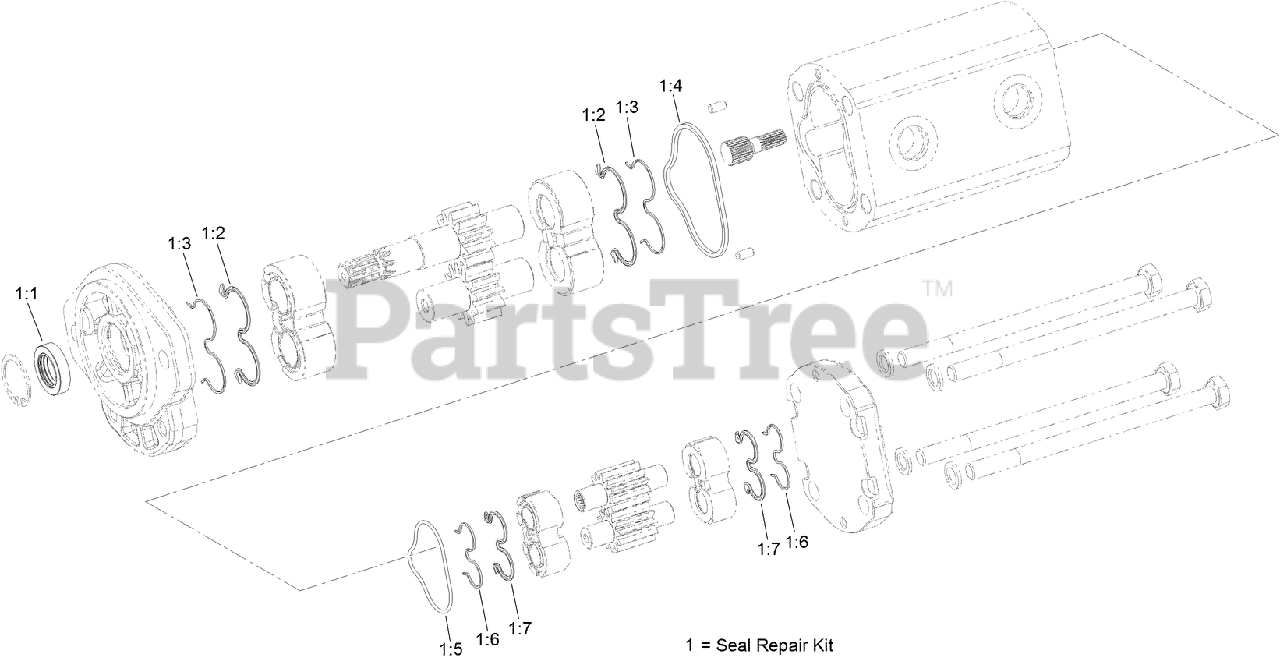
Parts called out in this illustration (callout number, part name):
1	SEAL KIT
1:1	SEAL-Shaft
1:2	SEAL-GEAR
1:3	RING-BACKUP
1:4	SEAL-SQUARE
1:5	O-RING
1:6	RING-BACKUP
1:7	SEAL-GEAR, REAR
